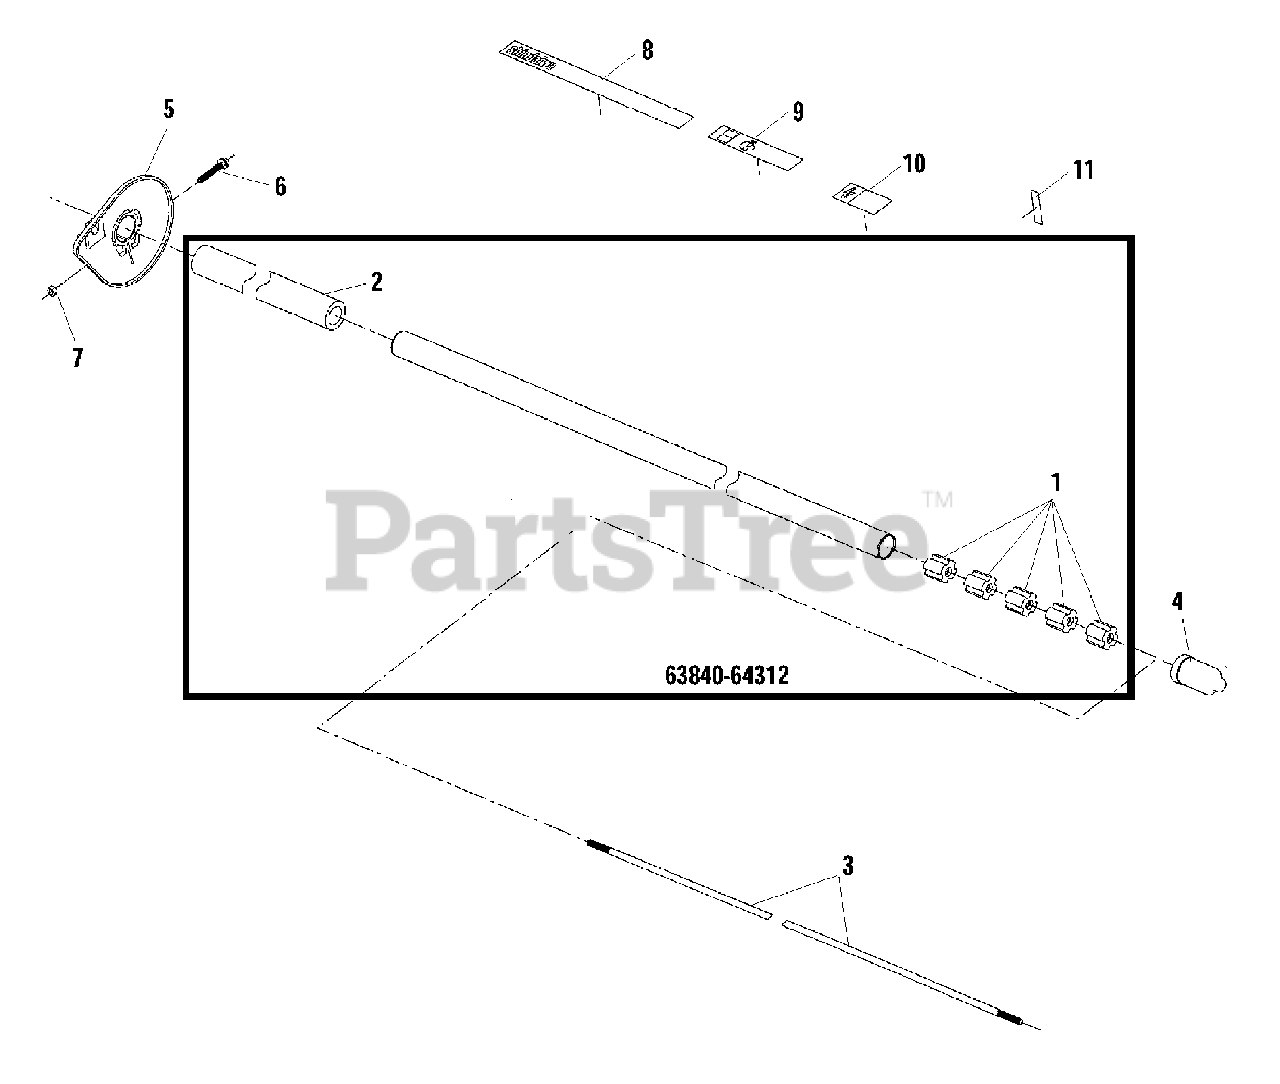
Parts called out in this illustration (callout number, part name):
1	BUSHING
2	GRIP - FRONT
3	PIPE, MAIN
4	CAP
5	PROTECTOR
6	SCREW - 5X30
8	LABEL - MODEL
9	LABEL - CAUTION
10	LABEL - HIGH VOLTAGE
11	LABEL - HANDLE LOCATION
63840-64312	MAIN PIPE ASSY
